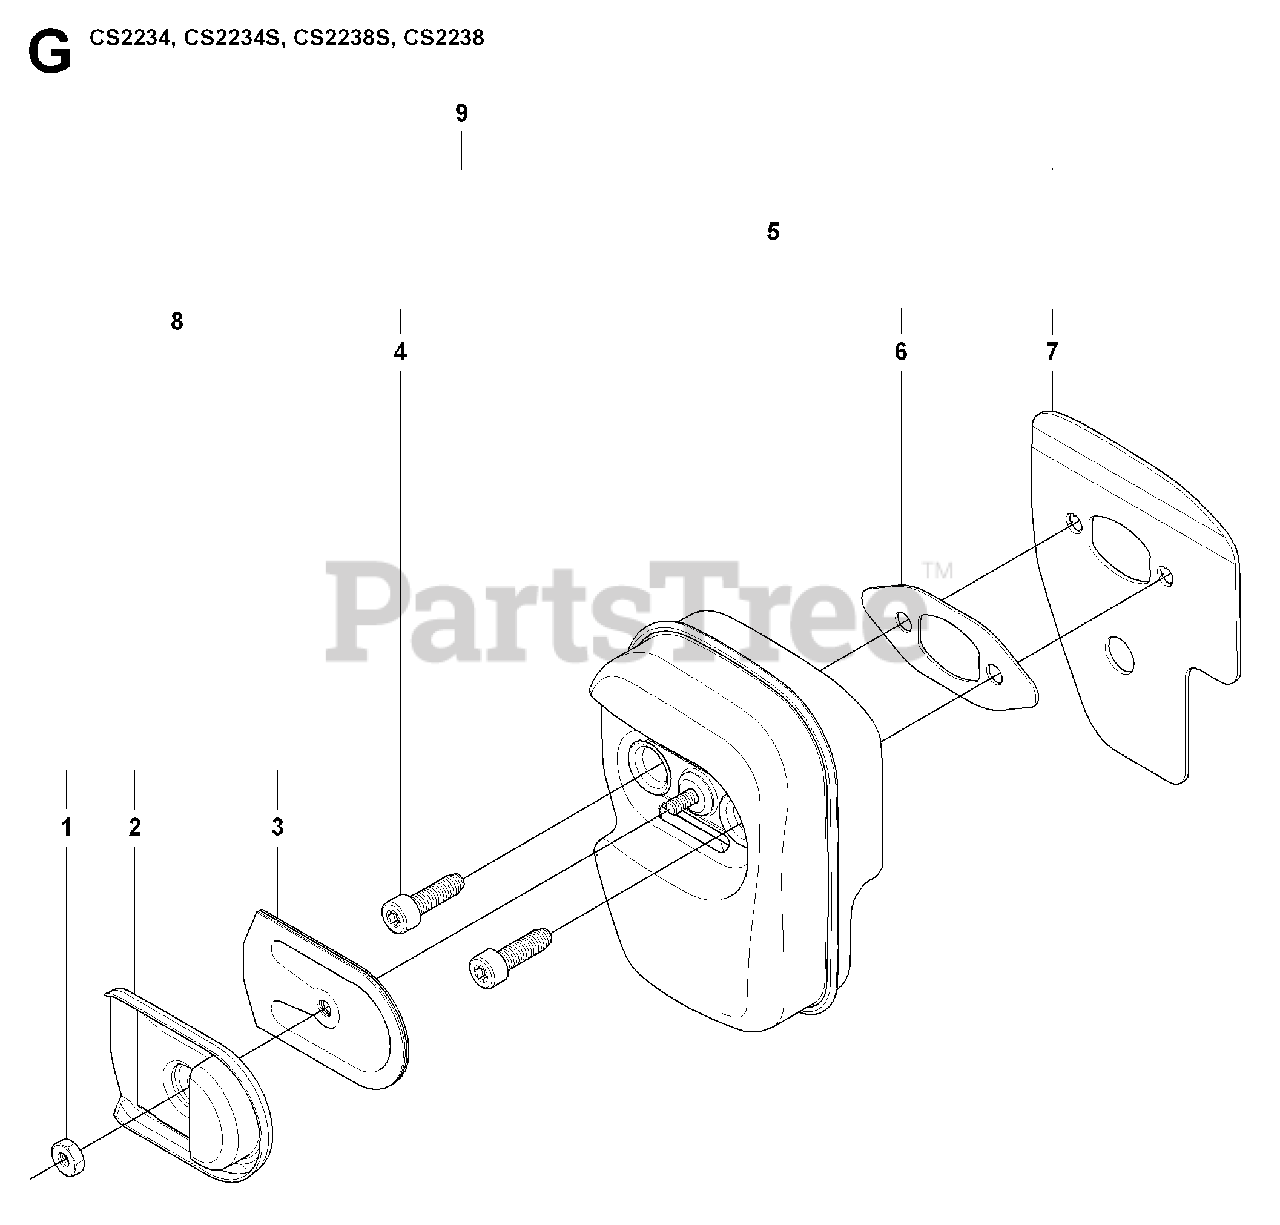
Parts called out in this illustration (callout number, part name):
1	%NUT-BRASS
2	EXHAUST PLATE
3	SCREEN ARRESTOR
4	SCREW MUFFLER
5	MUFFLER ASSY
6	GASKET
7	PLATE
8	KIT SPARK ARRESTOR
9	MUFFLER KIT
